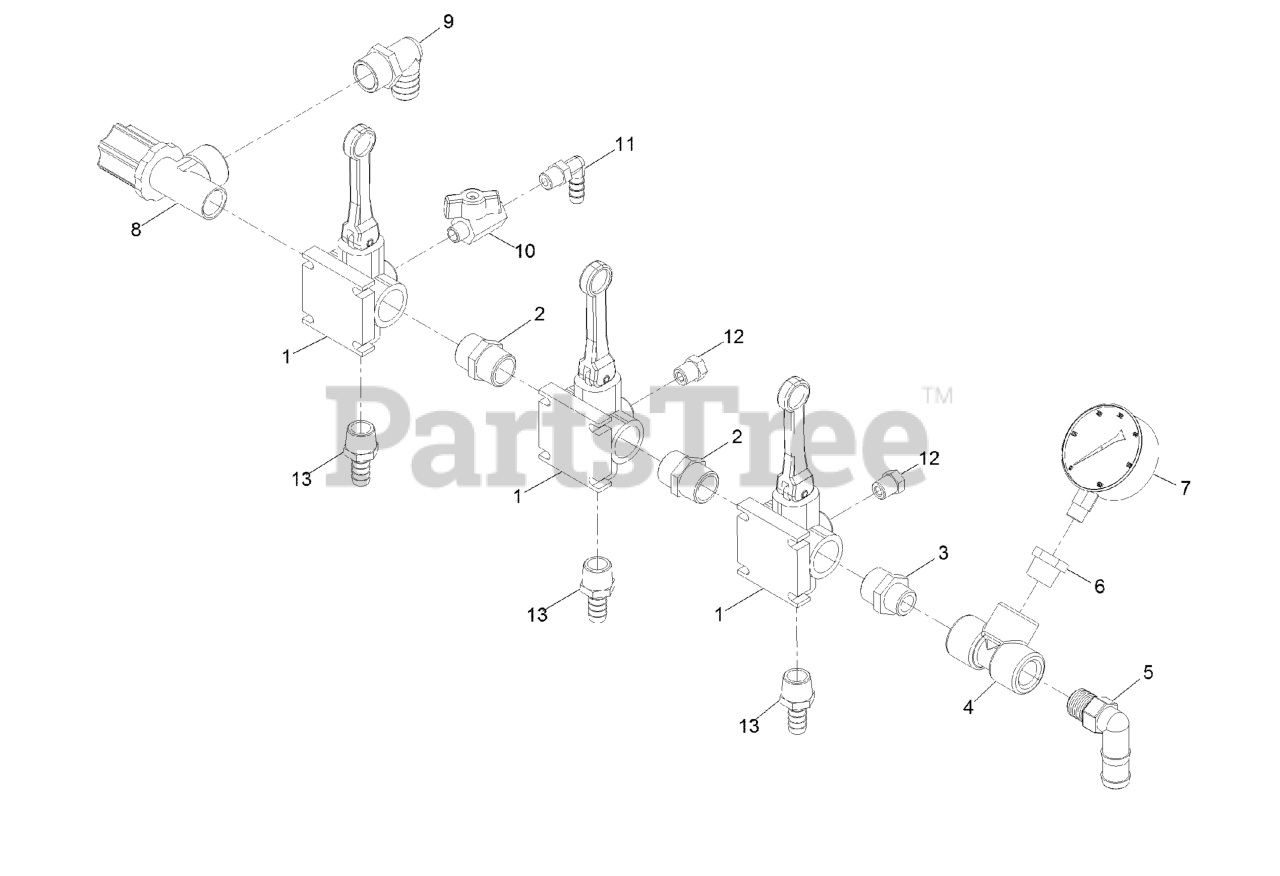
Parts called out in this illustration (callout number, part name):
1	VALVE-DIRECTO
2	FITTING-NIPPLE
3	FITTING-NIPPLE
5	ELBOW-90
6	FITTING-REDUCER
7	GAUGE
8	VALVE-THROTTLE
9	FITTING-ELBOW, 90
10	VALVE-CHROME, 1/4
11	FITTING-ELBOW, 90
12	PLUG-VALVE
13	FITTING-HOSEBARB
